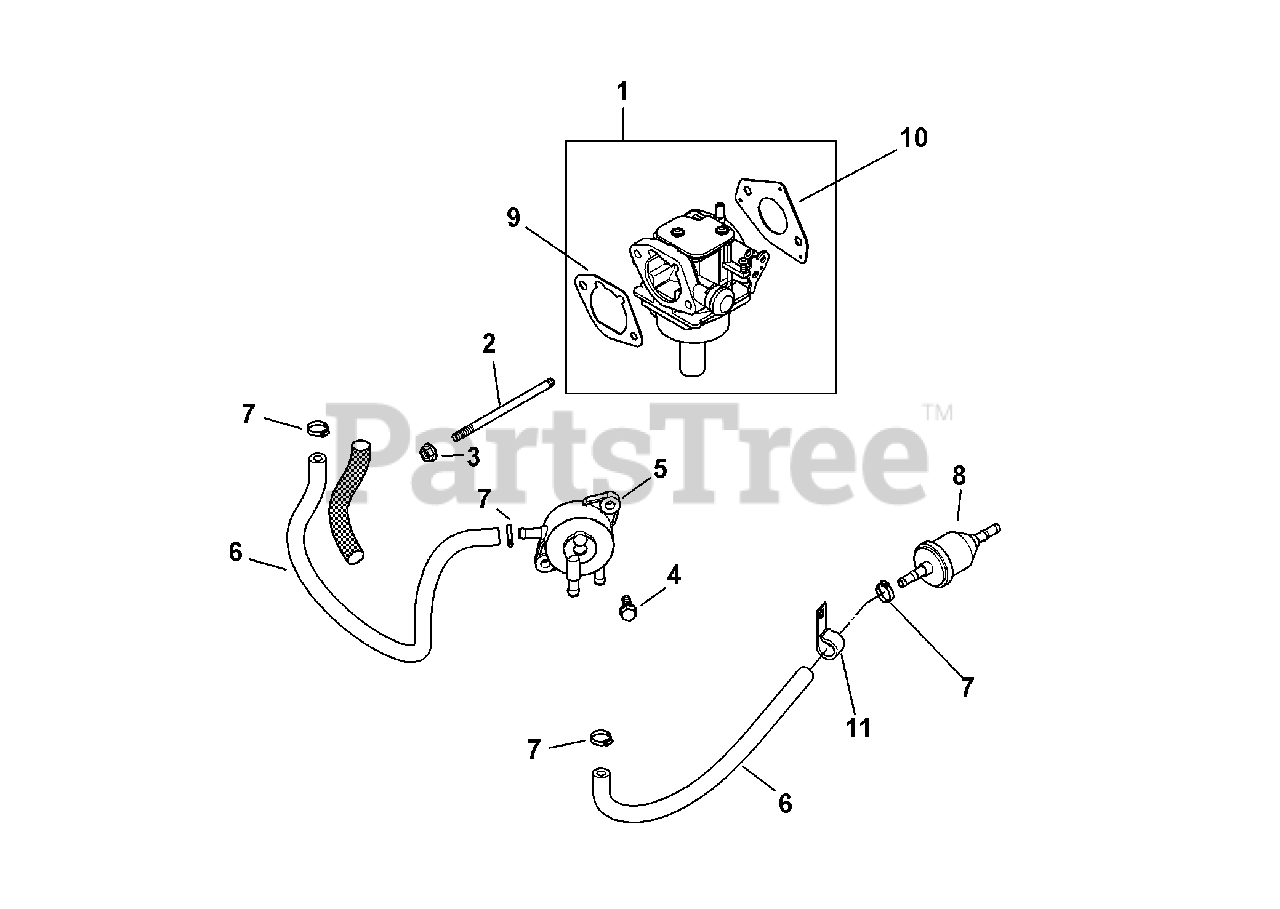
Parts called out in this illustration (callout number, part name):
1	Carburetor Kit
2	Stud, M6 x 1.0 x 106
3	Flange Nut, M6 x 1.0
4	Tap Screw, M6 x 1.7 x 18
7	Hose Clamp, 1/2
